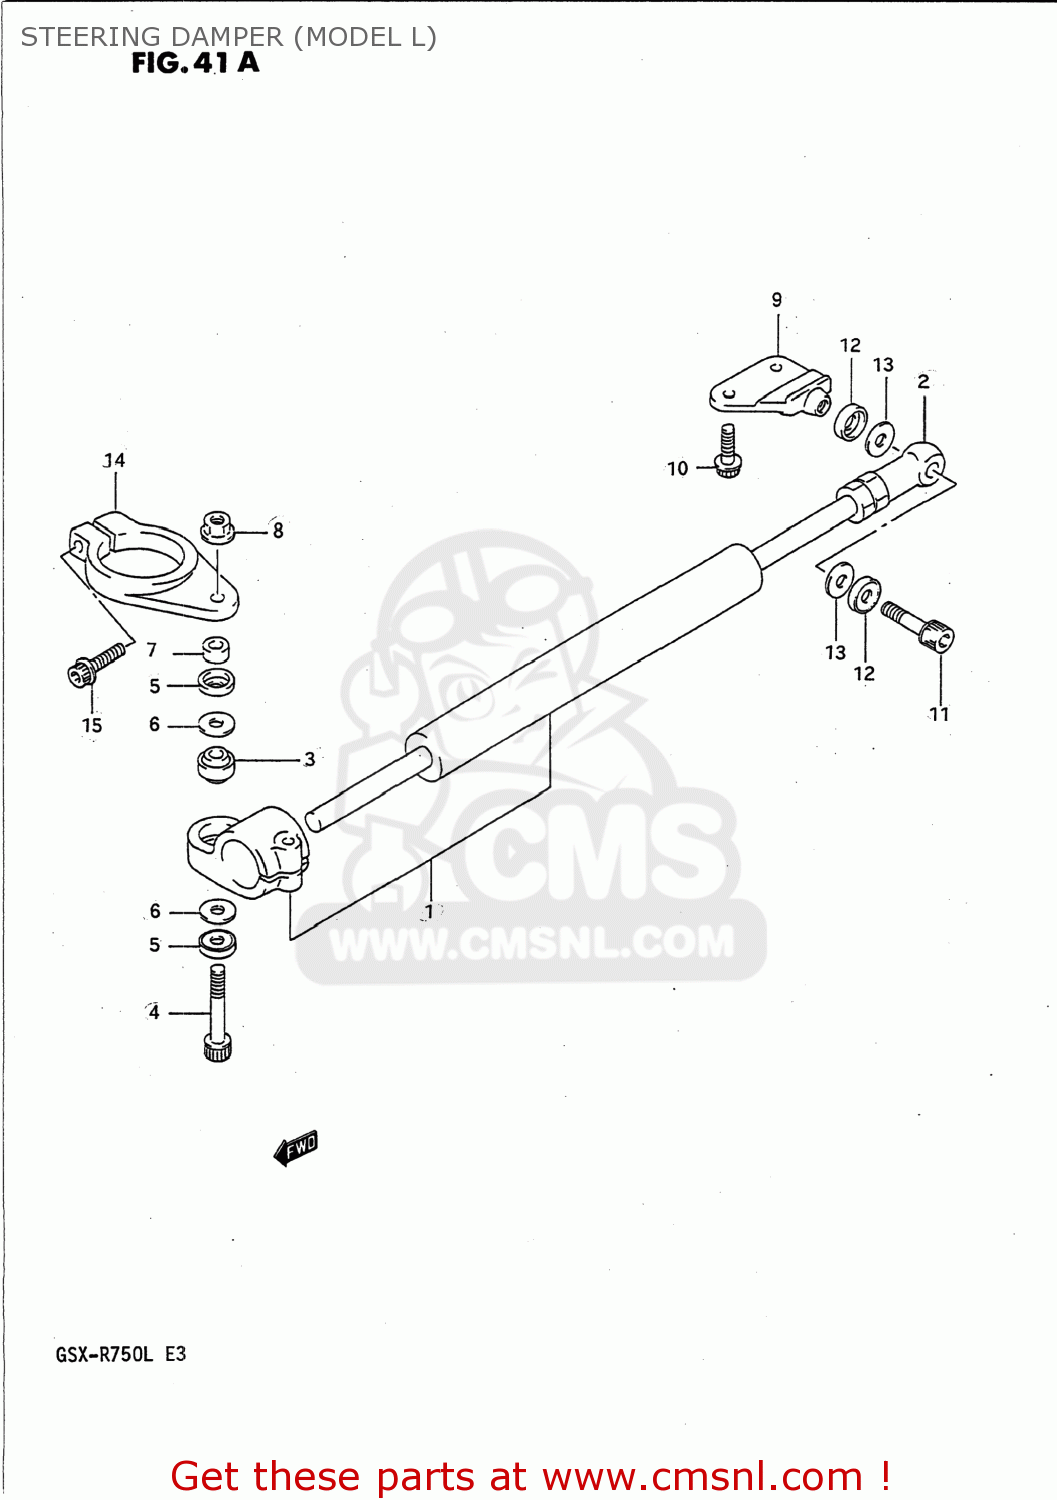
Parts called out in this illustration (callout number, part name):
1	DAMPER ASSEMBLY,STEERING
2	PILLOW BALL,ROD END
3	BEARING(8X17.5X11)
4	BOLT
5	6
6	SHIM
7	SPACER (8.4X14X6)
8	NUT
9	BRACKET,STEERING DAMPER FORK
10	BOLT,BRACKET
11	BOLT, FRONT RH
12	13
13	SHIM
14	BOSS,STEERING DAMPER
15	BOLT,BRACKET
